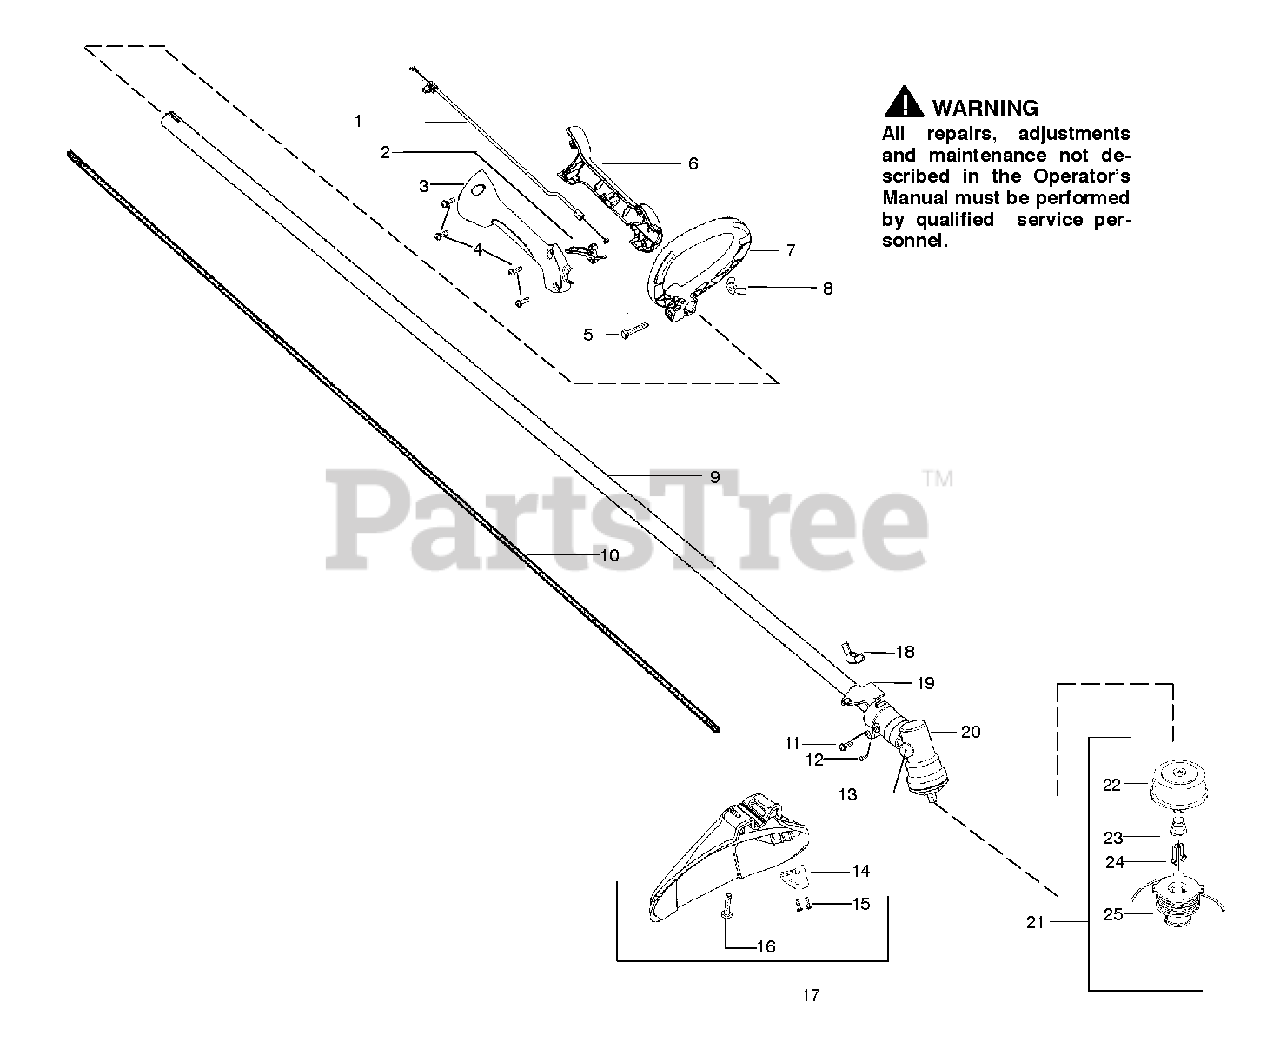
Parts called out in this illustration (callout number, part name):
1	ASSY THROTTLE CABLE
2	TRIGGER RED
3	HSG THROTTLE RH
5	BOLT\-1/4-20X1-1/2
6	HSG THROTTLE LH
7	ASSY ASSIST HANDLE
8	WINGNUT, TYPE 2
9	ASSY DRIVE SHAFT
10	SHAFT FLEX 52"
11	SCREW - CARB. ADAPTOR
13	PLUG GREASE 8MM
14	LINE LIMITER 17"
15	SCREW - THROTTLE HOUSING
16	BOLT, TYPE 2
17	KIT SHIELD
18	WINGNUT, TYPE 2
19	BRACKET SHIELD
20	GEARBOX ASSY 3/4
21	ACCY PLN TNG 6 HEAD LH 3/8"
22	TNG VI HUB ASSY LH
24	RETAINER
25	TNG 6 LH .080 X 25' PLN
